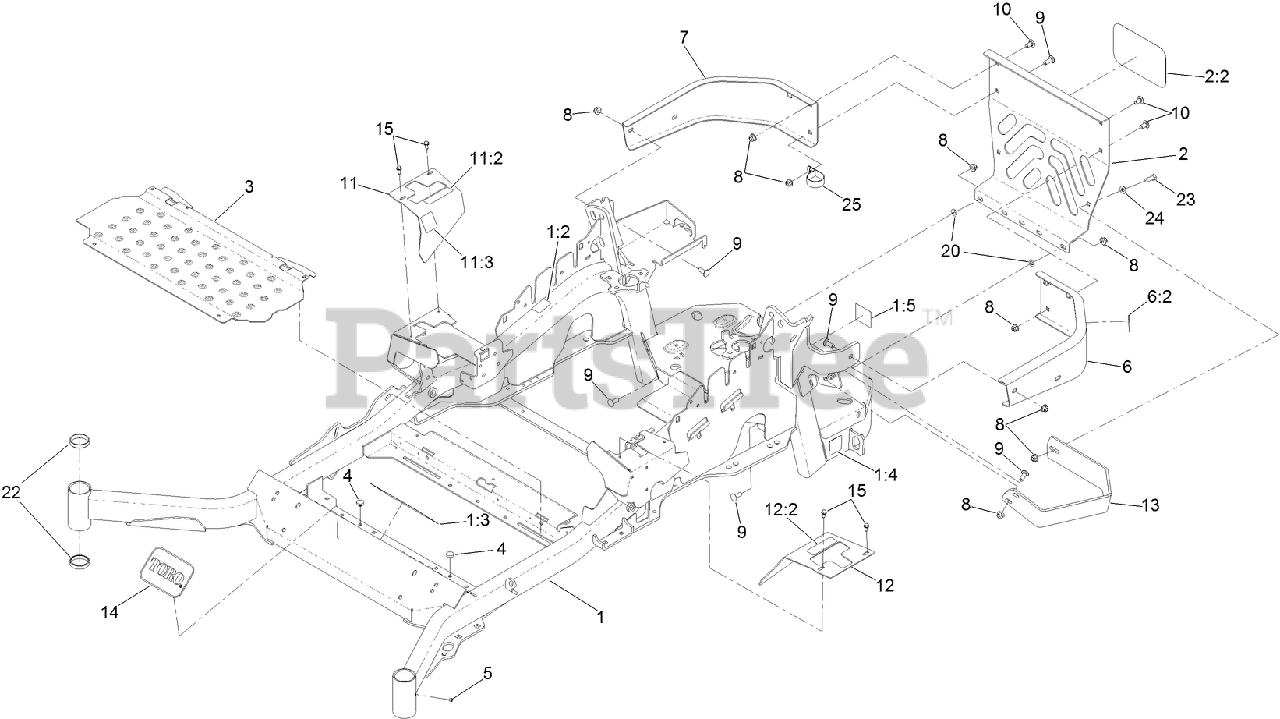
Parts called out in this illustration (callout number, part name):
1	MAINFRAME ASM
1:2	DECAL-WARNING
1:3	DECAL-DANGER
1:4	DECAL-HAZARD, PINCHED FINGER
1:5	DECAL-SPARK ARRESTER
2	REAR GUARD ASM
2:2	DECAL
3	FLOORPAN
4	BUMPER
6	LH BUMPER ASM
6:2	DECAL-WARNING
7	BUMPER-RH
8	NUT-HF, NI
9	SCREW-CARR
10	SCREW-CARR
11	RH MOTION CONTROL COVER ASM
11:2	DECAL-CONTROL, MOTION
11:3	DECAL-PARK BRAKE, CE
12	LH MOTION CONTROL COVER ASM
12:2	DECAL-CONTROL, MOTION
13	GUARD-MUFFLER
14	DECAL
15	SCREW-HWH
20	NUT-PUSH
22	CUP-BEARING
23	SCREW-HH
24	WASHER-FLAT
25	CLAMP-R
